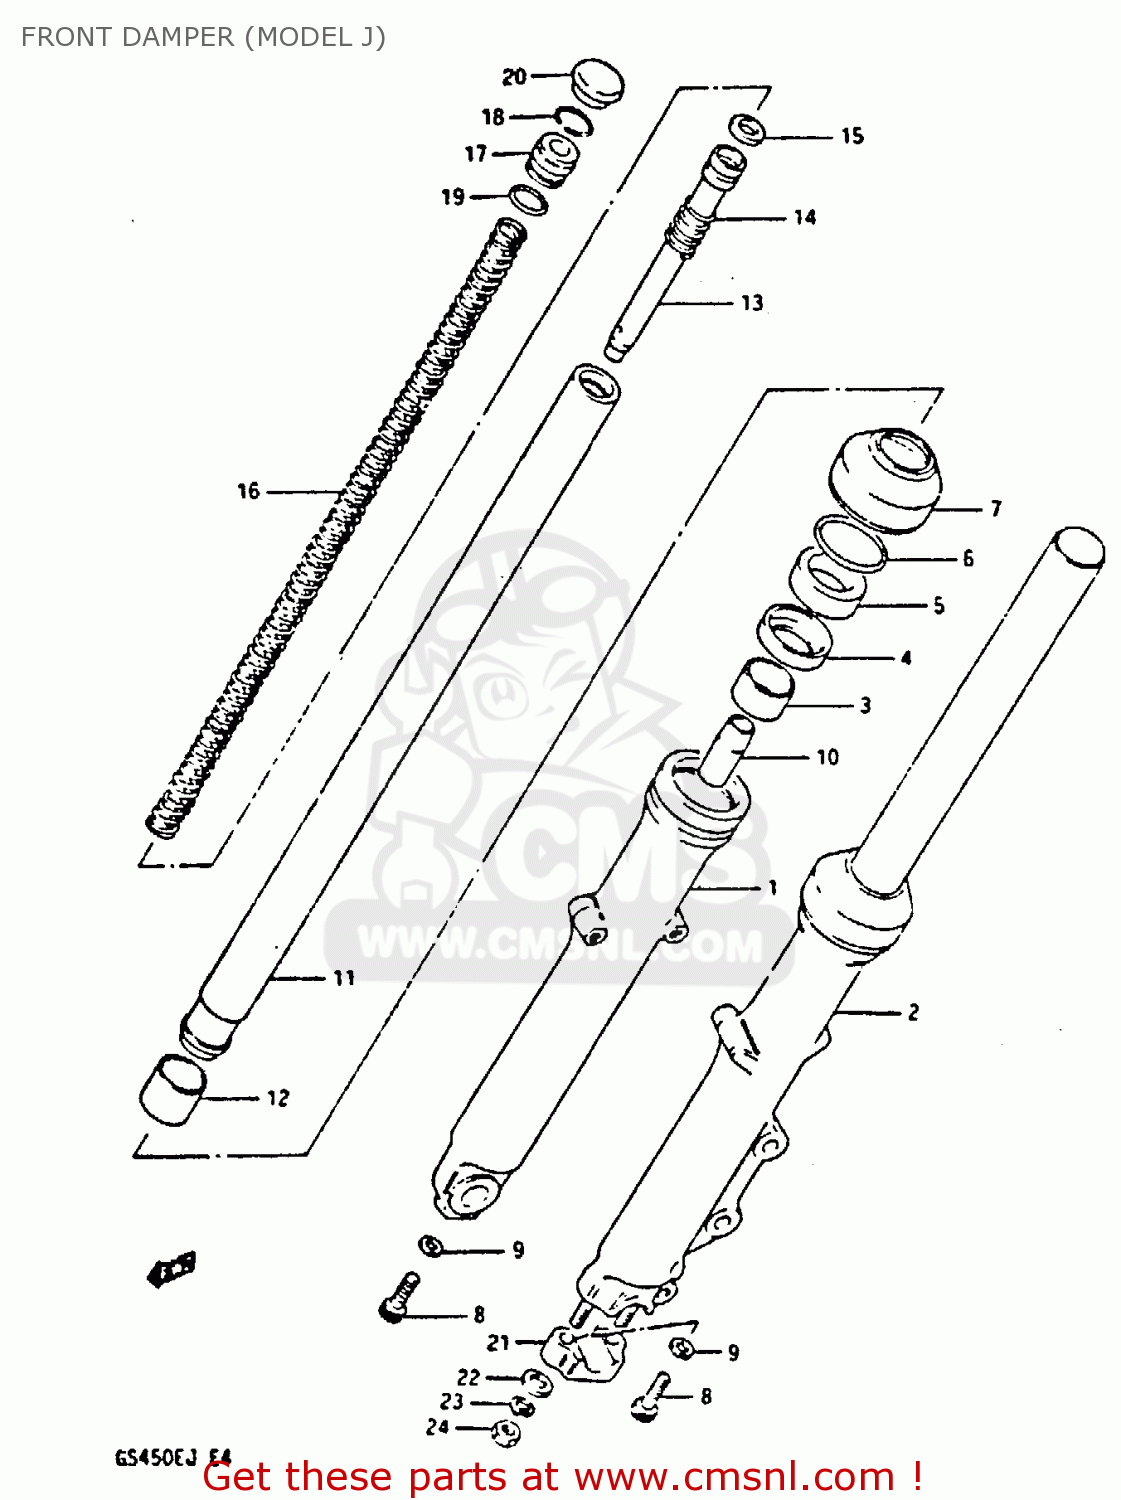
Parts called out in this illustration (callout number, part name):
1	OUTER TUBE, RH
2	OUTER TUBE, LH
3	BUSH,GUIDE
4	SPACER,OIL SEAL
5	SEAL,OIL
6	RING,OIL SEAL STOPPER
7	DUST SEAL
8	BOLT(8X27)
9	GASKET (NAS)
10	PIECE,OIL LOCK
11	TUBE,FORK,INNER
12	BUSH
13	CYLINDER,FRONT FORK
14	SPRING,REBOUND
15	RING,PISTON
16	SPRING,FRONT FORK
17	SEAT,SPRING
18	RING,STOPPER
19	O RING
20	CAP,FRONT FORK
21	HOLDER,AXLE
22	WASHER
23	LOCK WASHER
24	NUT
